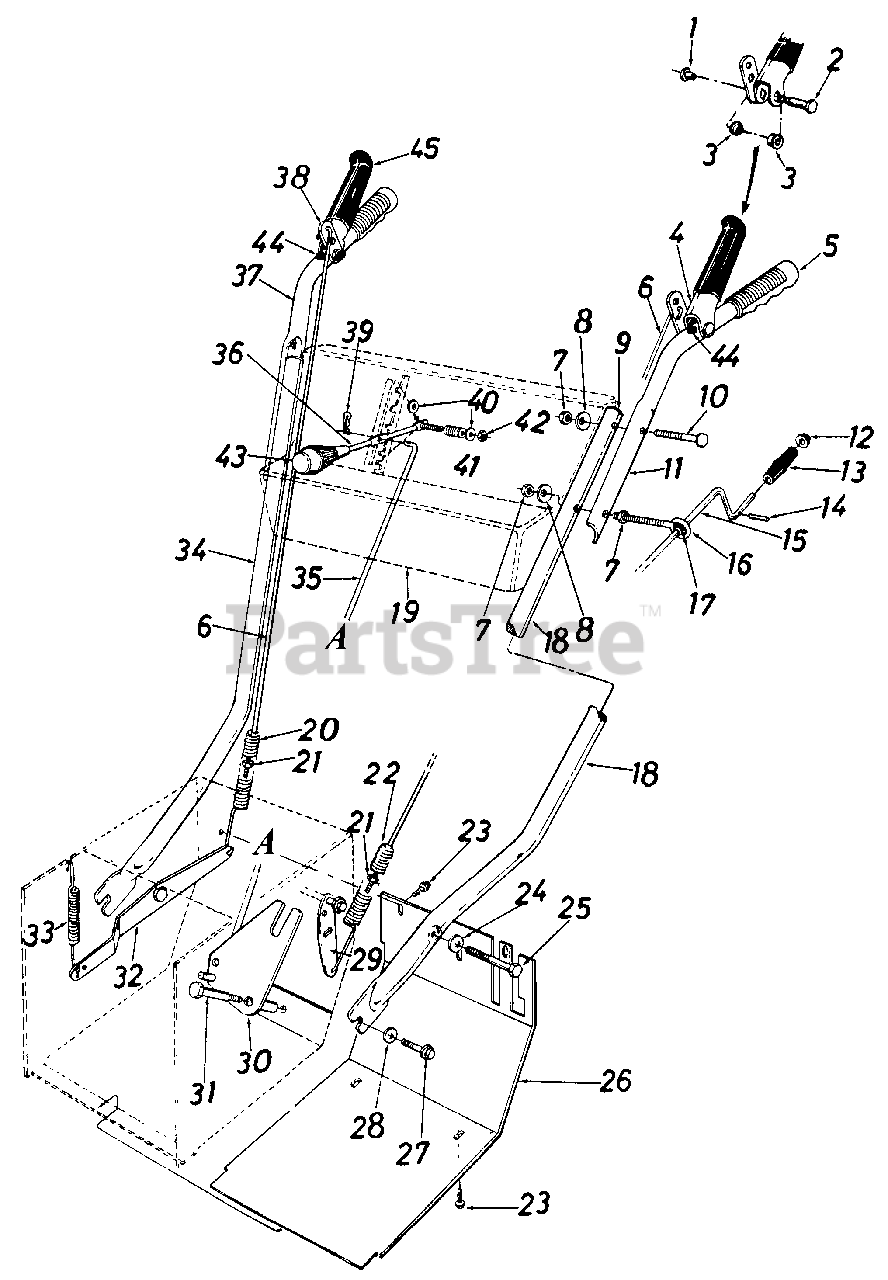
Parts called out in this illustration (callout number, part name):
1	NUT-SHLD
2	SCREW-SHLD .374 DIA X1.530
3	BEARING-FLANGE
4	GRIP ASSY-LH CLUTCH 2-STG S/T MTD
5	GRIP-BLACK
6	ROD-LOCKOUT STIC
7	NUT-HEX 5/16-18
8	WASHER-BELL .337 X .867 X .057
10	BOLT-CARRIAGE 5/16-18 X 2.00
11	HANDLE-FOLDING-LH PAINTED
13	KNOB-CHUTE CRANK
14	PIN-ROLL 1/18 DIA
15	CRANK ASSY-CHUTE
17	BUSHING-.380 ID
18	HANDLE-LOWER-LH PAINTED
19	PANEL ASSY-HANDLE
20	SPRING-EXTENSION
21	NUT-INS LOCK 1/4-20
23	SCREW-HEX WASH SF TAPP
24	WASHER-BELL .400 ID X .88 X .060
25	SCREW-HEX 3/8-16 X 2.00
26	COVER-FRAME
27	SCREW-PILOT 3/8-16 X .88
28	WASHER-BELL .400 ID X .88 X .060
29	BRACKET ASSY-DR CLUTCH
32	BRACKET-AUG CLUTCH
33	SPRING-EXTENSION
34	HANDLE-LOWER-RH PAINTED
36	HANDLE-SHIFT
39	PIN-INTERN COT-5/16 DIA
40	WASHER-FL-.344 X .62
41	SPRING-COMPRESSION
42	NUT-HEX INS L-5/16-18
44	CAP-PUSH
45	VINYL-PLASTIC
